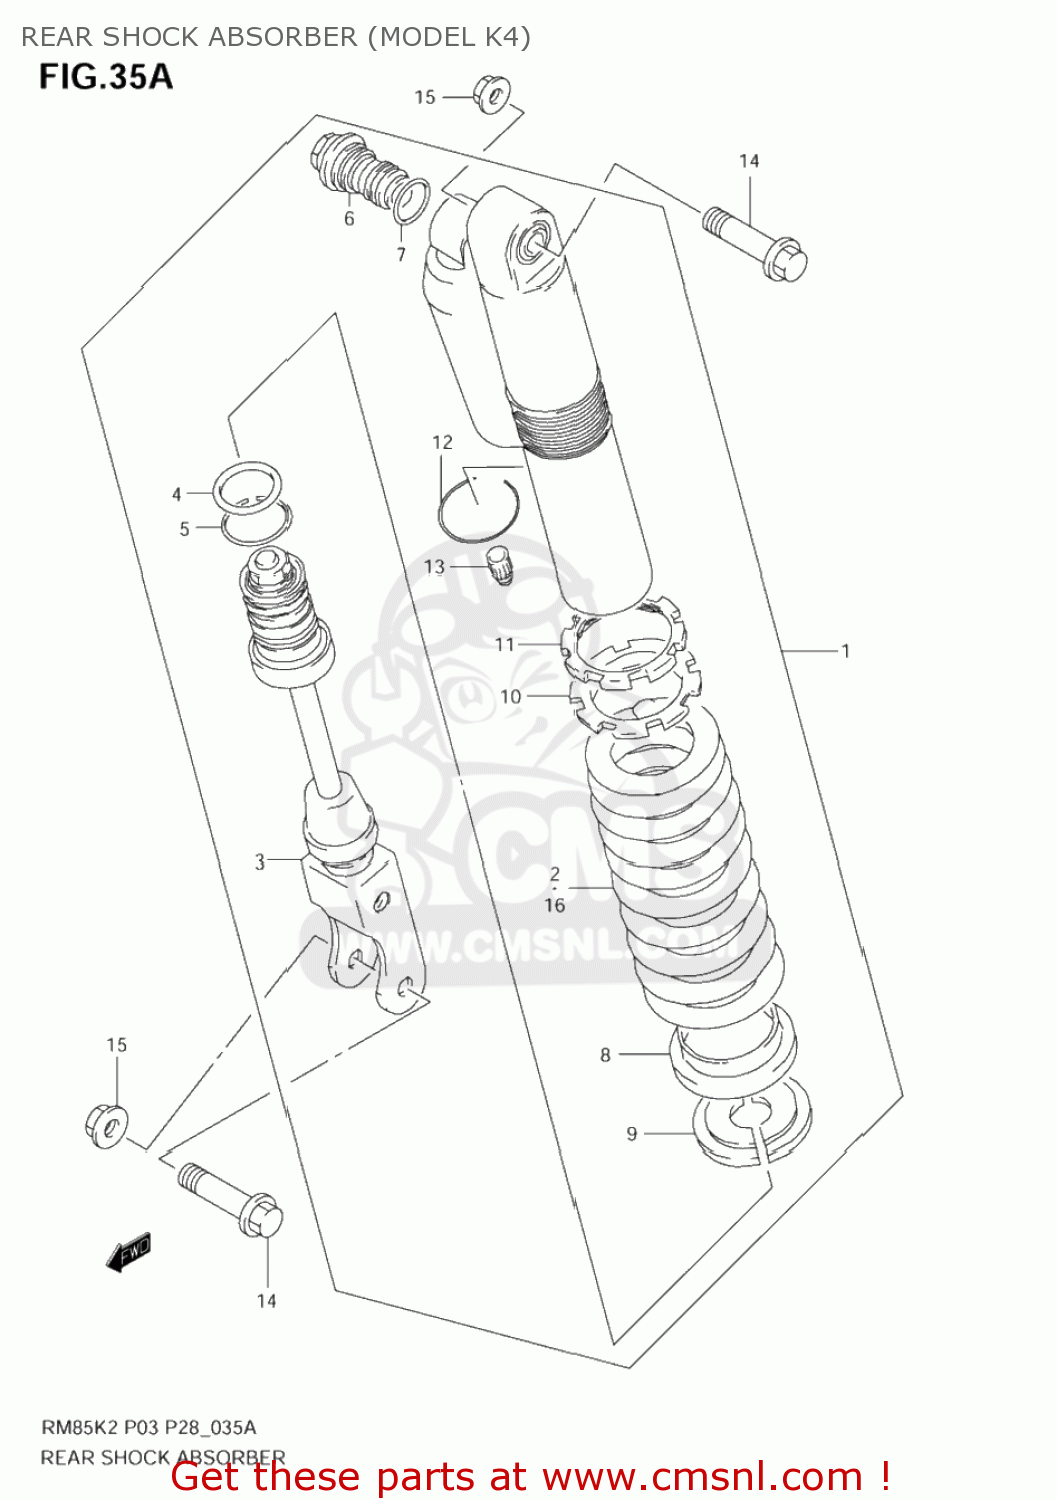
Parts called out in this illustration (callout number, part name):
1	ABSORBER ASSY,RR SHOCK(YELLOW)
2	SPRING,RR(K=4.8)
3	ROD,PISTON
4	O RING
5	RING,STOPPER
6	BOLT,PLUG
7	O RING
8	SEAT,SPRING
9	SEAT,SPRING STOPPER
10	ADJUSTER,SPRING
11	NUT,SPRING ADJUSTER
12	RING,STOPPER
13	CAP
14	BOLT,RR CUSHION ROD UPR
15	NUT
16	SPRING,RR(K=4.6)
